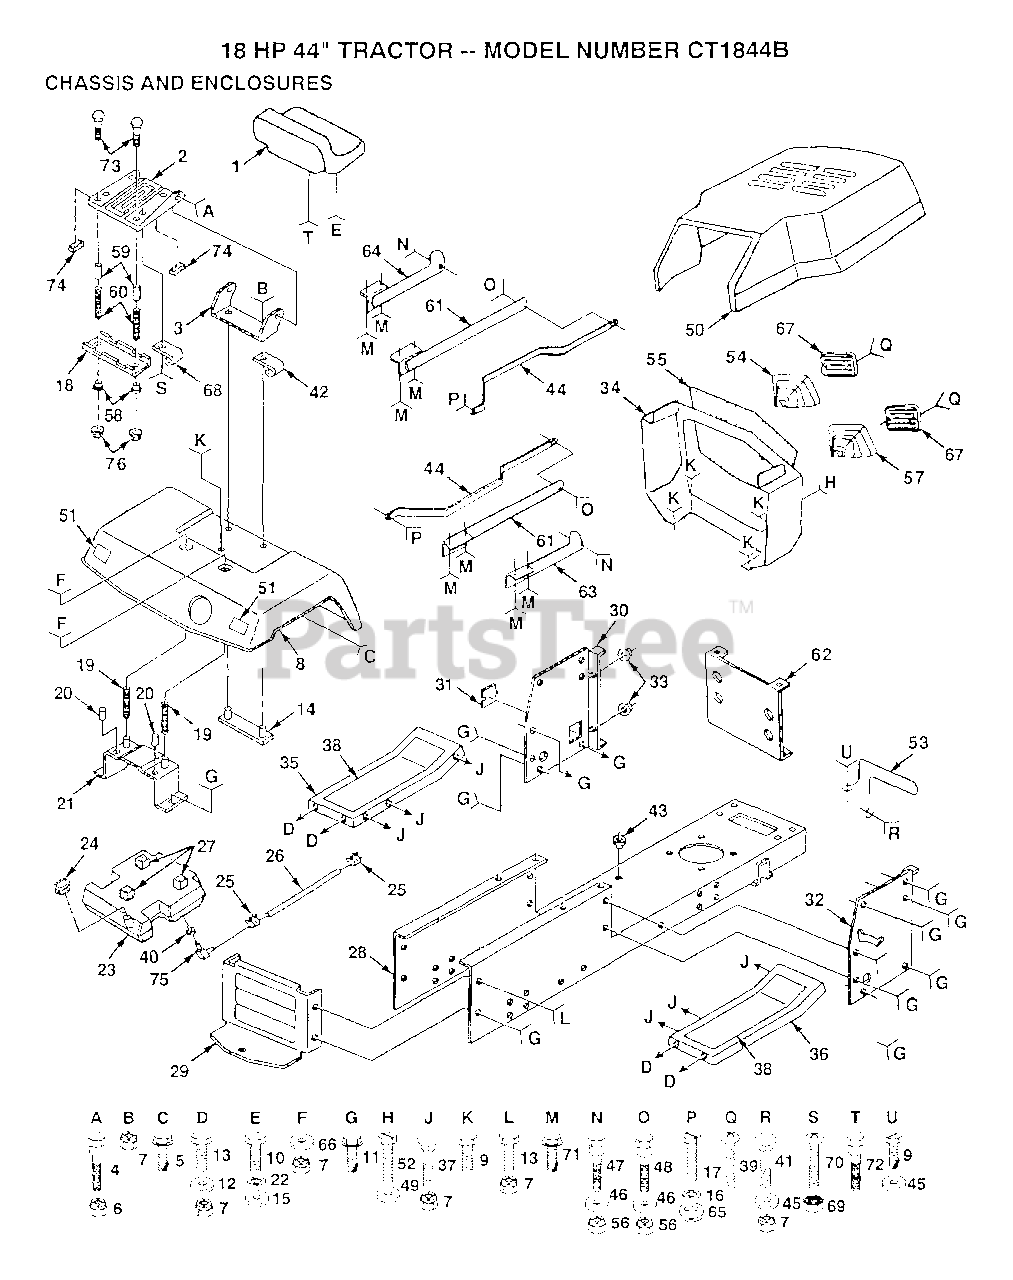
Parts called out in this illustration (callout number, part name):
3	BRKT PIVOT SEAT
5	SCREW LT
9	SCREW GTV
10	BOLT
11	SCREW
12	WASHER
15	WASHER
16	LOCKWASHER
17	BOLT LT
18	BRKT SWITCH
19	SPRING COMPRESSIO
20	NUT-PUSH YT
22	LOCKWASHER
25	HOSE CLAMP
27	PAD-SPACER LT
28	CHASSIS
31	COVER ACCESS
33	SNAP BUSHING T
37	BOLT
38	FOOTREST PAD
40	BUSHING OUTLET T
41	BOLT D
42	CLIP T
45	WASHER HYT
47	BOLT T
48	"BOLT,SHOULDER"
51	REFLECTOR-TAIL YT
52	SCREW
53	GUARD MUFFLER HYT
55	SCREEN GRILL GTV
58	BUSHING
59	SPACER SPLIT
60	SPRING COMPRESSED
61	STRAP ASSY-REAR T
63	STRAP ASSY T
64	STRAP ASSY T
66	WASHER
69	"NUT,KEPS"
72	"BOLT,SHOULDER"
74	STRIP FORM
75	FUEL TANK STEM GT
